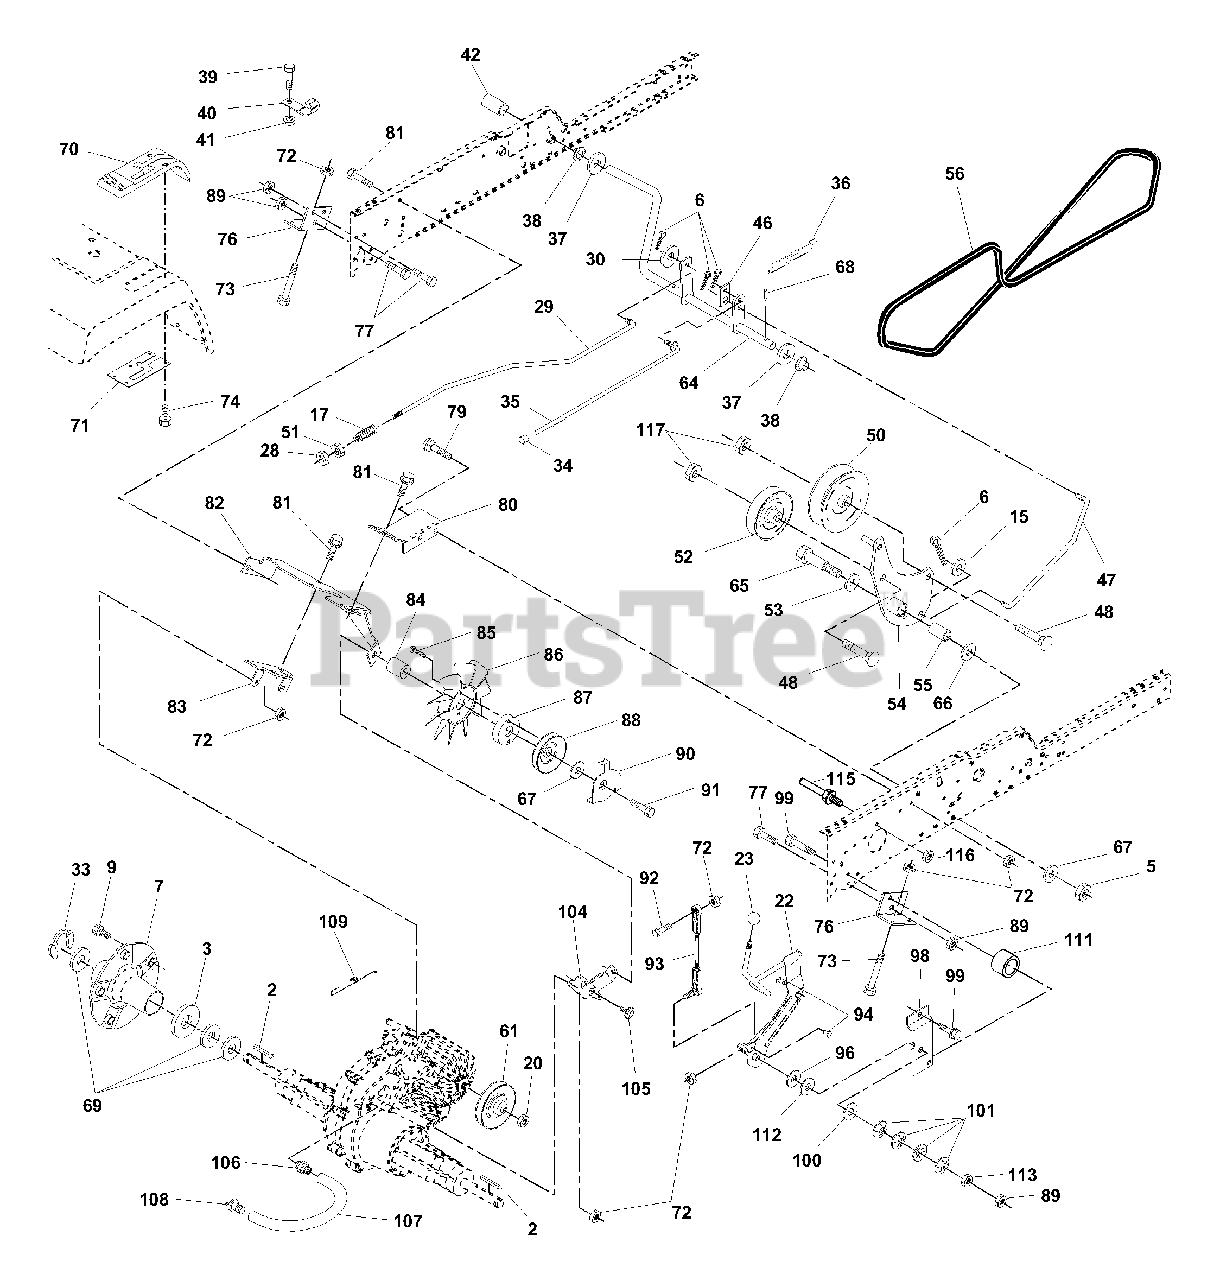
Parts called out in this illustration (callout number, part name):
2	Key 1/4 x 2.5
3	Washer Thrust Axle Harden
5	Nut Crownlock 3/8-16
6	Pin Cotter 1/8 x 3/4
7	Wheel Hub Asm.
15	Washer 13/32 x 13/16 x 16 Ga.
17	Spring Rod Brake
20	Nut Hex Jam Toplock 1/2-20
22	Shaft Arm Asm
28	Nut, Hex Jam 3/8-16
30	Washer 13/32 x 1 x 14Ga
34	Cap Plunger
35	Rod Parking Brake
36	Spring Extension
37	Washer 25/32 x 1-1/4 x 16 Ga.
39	Screw Fin #10-24 x 1
40	Actuator Interlock Switch
41	Nut Toplock #10-24 Unc
42	Cover Pedal
46	Retainer Spring
47	Clutch Rod
48	Bolt Carriage 3/8-16 x 1-1/2 Gr. 5
50	Pulley Idler Flat
51	Nut, Crownlock 3/8-16
52	Pulley Idler Grooved
53	Washer Hartdened
54	Arm Asm Idler Clutch 98
55	Bearing,Idler
61	Pullery Transaxle
64	Shaft Asm Brake Parking Clutch
65	Bolt Shoulder
66	Washer Hardened
67	Washer 13/32 x 13/16 x 12 Ga
70	Console Hydro Fender
71	Plate Console Shift
72	Locknut Hex W/Washer Insert
73	Bolt Hex Flghd 5/16-18 x 3 Gr. 5
74	Screw, Hex Wsh Hi-Lo 1/4-1/2
76	Bracket Transaxle
77	Bolt Fin Hex 7/16-14 x 1
79	Bolt Carriage 5/16-18 x 5/8
80	Bracket Torque RH
81	Screw 3/8-16 x 3/4
82	Bracket Mount Torque/Fan
83	Strap Torque Mid
85	Screw #10-24 x 1-1/4
86	Fan 7" Hydro
87	Adapter Fan
88	Pully Idler V-Groove Flange
89	Nut, Crownlock 7/16-14
90	Keeper Belt
91	Screw Thdrol 3/8-16 x 2-3/4
92	Bolt Fin Hex 5/16-18 x 1.75
93	Link Shift Asm
94	Fastner Christmas Tree
96	Washer Nickel Plated
98	Bracket Shift
99	Screw 3/8-16 x 1-1/2
100	Washer Compression
101	Washer Bellville
104	Bracket Idler
105	Screw Tap 1/4-20 x 1/2
106	O-Ring Asm Hydro Gear
107	Line Fuel Hydro 15" VGT Serv
108	Cap Asm Vent Hydro Gear
109	Spring Return Brake
111	Spacer Shift Lever VGTH
112	Washer Nylon High Temp
113	Nut Hex ASF 7/16-14 Unc
115	Keeper Belt T/A GND DR LR
116	Nut Lock Hex Flange 5/16-18
117	Nut Lock Flg. 3/8-16 Unc
118	Nut Lock Hex W/Ins 5/16-18unc
